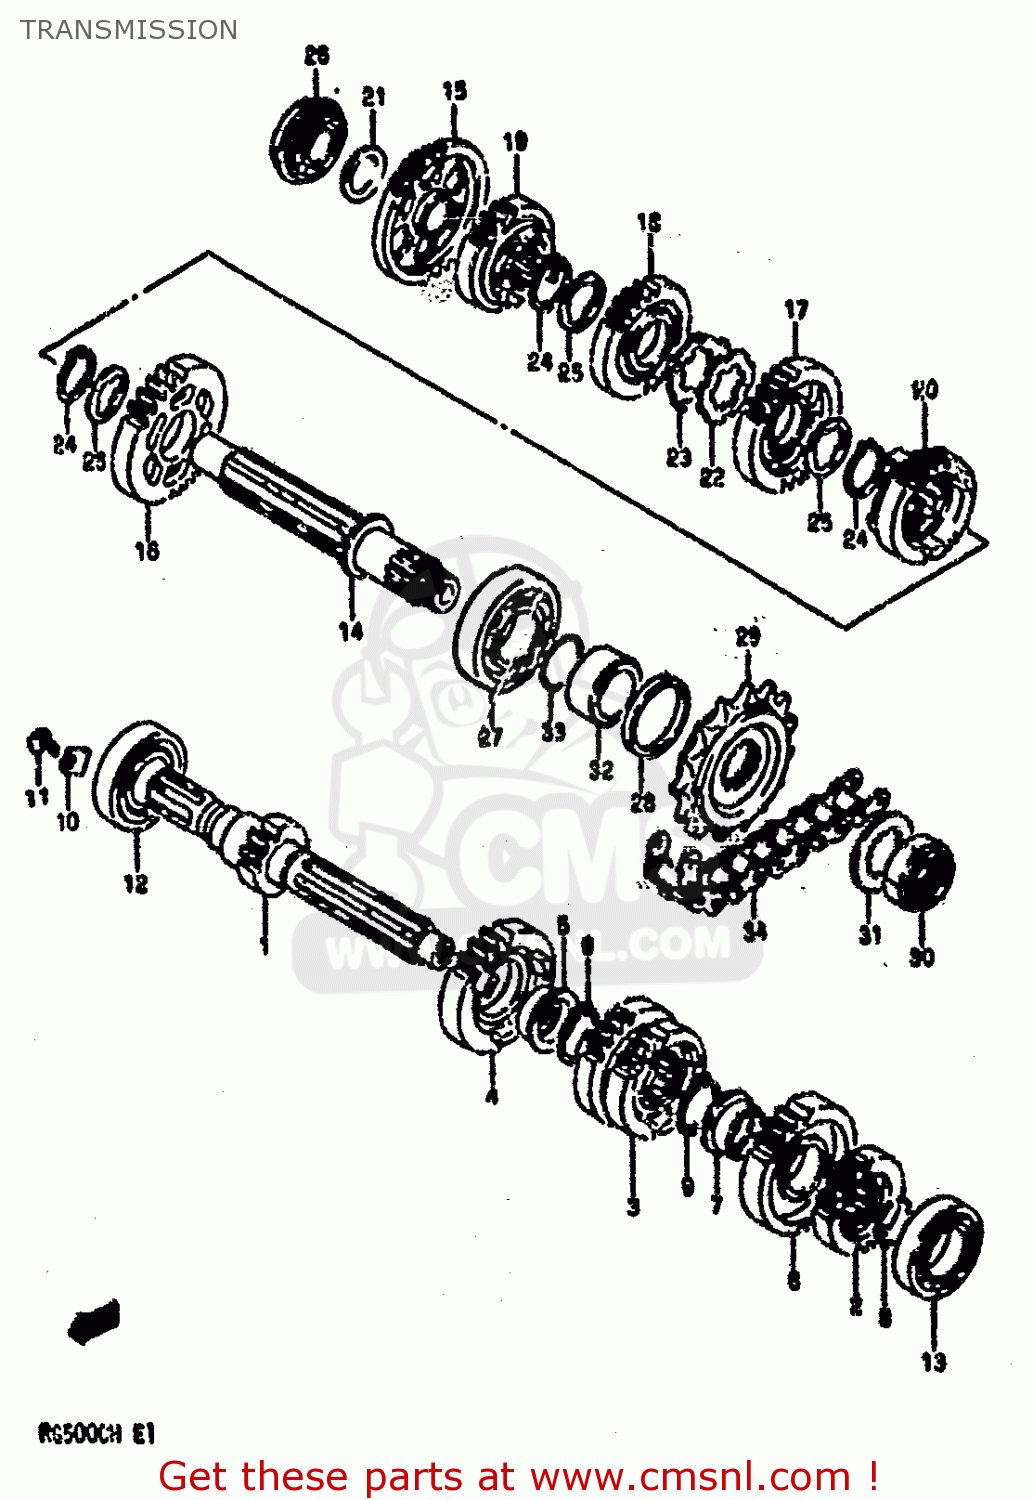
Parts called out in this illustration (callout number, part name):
1	COUNTER SHAFT (NT:11)
2	GEAR,2ND DRIVE (NT:16)
3	GEAR,3RD DRIVE
4	GEAR,5TH DRIVE (NT:22)
5	BUSH
6	GEAR,6TH DRIVE (NT:23)
7	BUSH
8	CIRCLIP
9	CIRCLIP
10	RETAINER,COUNTER BEARING,R
11	SCREW
12	BEARING(25X52X21)
13	BEARING
14	DRIVESHAFT
15	GEAR,1ST DRIVEN (NT:29)
16	GEAR,2ND DRIVEN
17	GEAR,3RD DRIVEN (NT:29) KIT
18	GEAR,4TH DRIVEN (NT:27)
19	GEAR,5TH DRIVEN (NT:23)
20	GEAR,6TH DRIVEN
21	WASHER,THRUST
22	WASHER,LOCK
23	WASHER
24	RING,SNAP
25	WASHER,LOCK
26	BEARING
27	BEARING
28	SEAL,OIL(32X42X6)
29	SPROCKET,ENGINE
30	NUT
31	WASHER,LOCK
32	SPACER(25X32X16.4)
33	O RING(D:1,ID:24.5)
34	CHAIN ASSEMBLY,DRIVE
